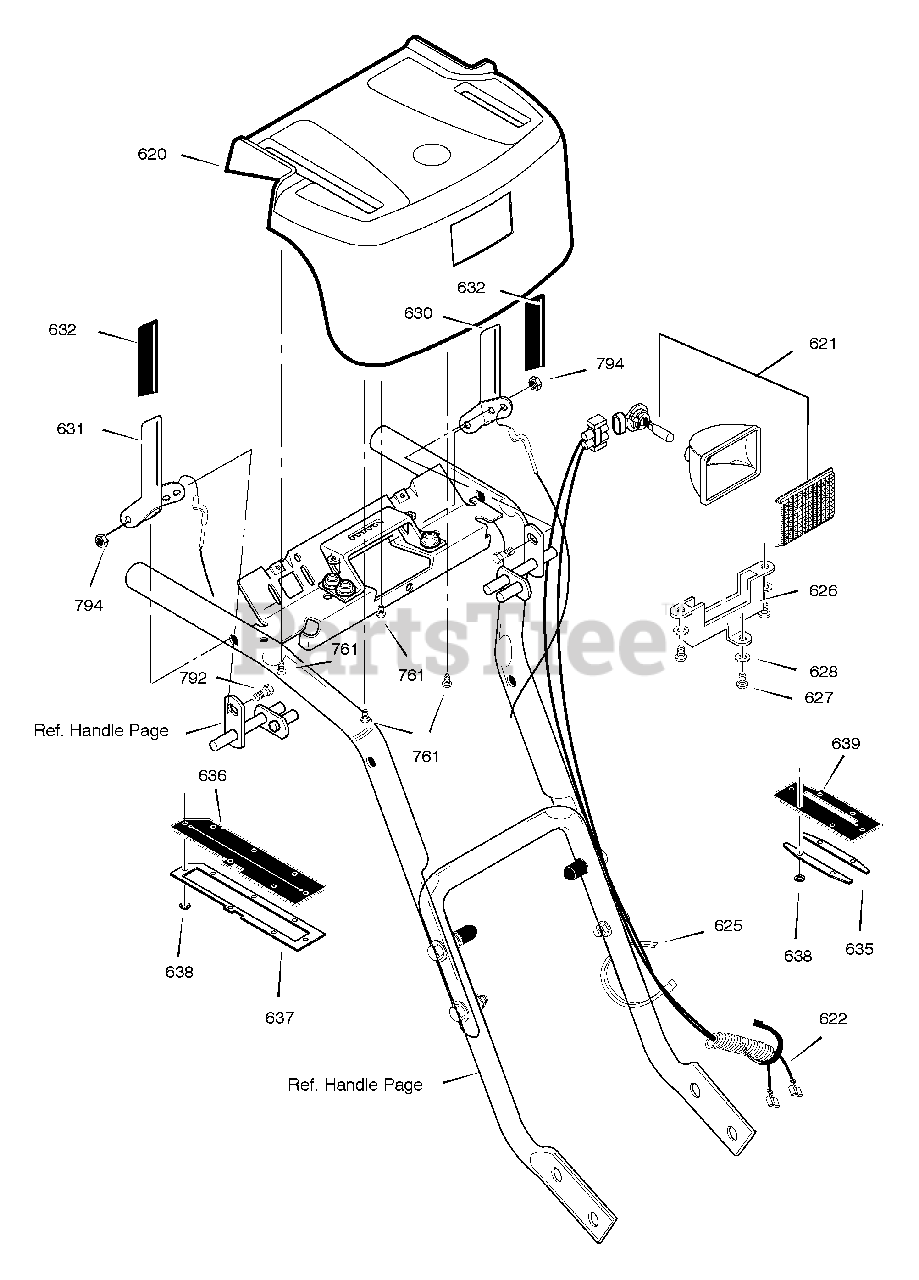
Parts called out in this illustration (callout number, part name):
620	PANEL, CONTROL W/LIGHT
621	LIGHT, HALOGEN
622	HARNESS, WIRE
625	TIE, CABLE
626	BRACKET, LIGHT
627	SCREW #8 X .50
628	WASHER, FLAT
630	CLUTCH HANDLE LH
631	CLUTCH HANDLE RH
632	GRIP, CLUTCH LEVER
635	FRAME, COVER
636	COVER, SPEED LEVER
637	FRAME, SPEED COVER
638	NUT, PUSH
639	COVER, CHUTE LEVER
792	BOLT, 1/4-20 X 0.50
794	NUT, 1/4-20
